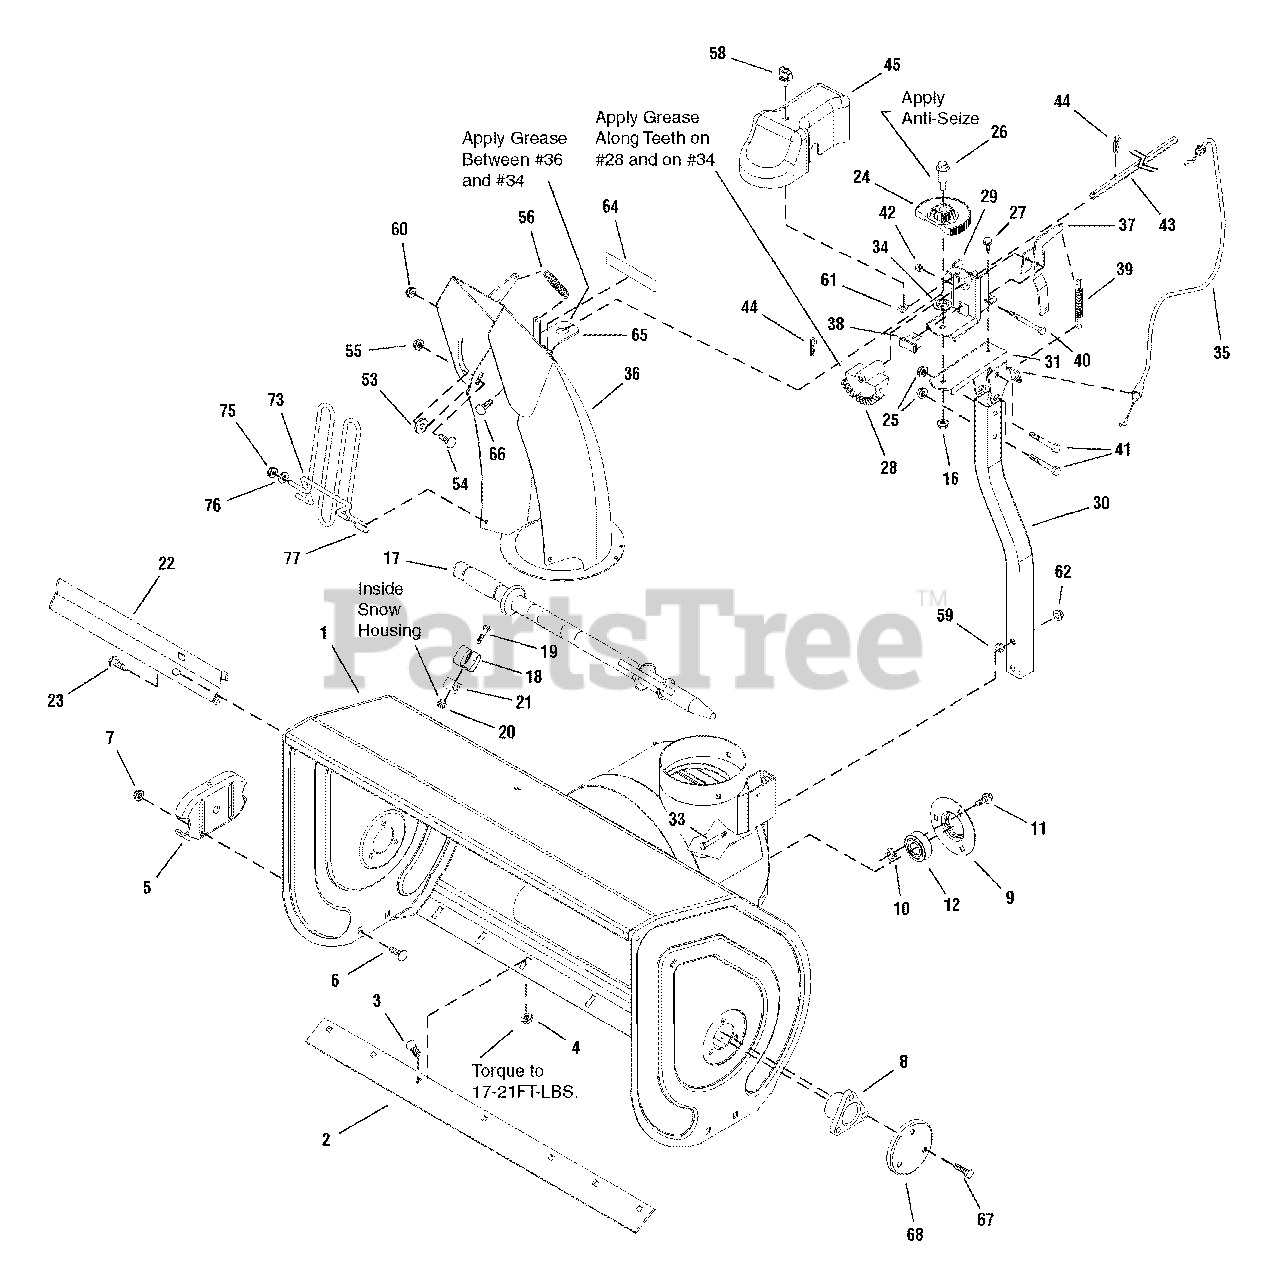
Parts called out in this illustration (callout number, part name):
1	HOUSING ASSEMBLY, 26"
1	HOUSING ASSEMBLY, 28"
1	HOUSING ASSEMBLY, 30"
1	HOUSING ASSEMBLY, 32"
2	BLADE, Scraper 26"
2	BLADE, Scraper 28"
2	BLADE, Scraper 30"
2	BLADE, Scraper 32"
3	CARRIAGE BOLT, 5/16-18 x 5/8 G5
4	NUT, Hex Flange 5/16-18 Two-Way Lock
5	SKID, Shoe Reversible
6	CARRIAGE BOLT 3/8-16 x 3/4 G5
7	NUT, Hex Flange 3/8-16 ESNA
8	BEARING, Flange
9	BEARING, Retainer
10	RETAINER, Nut, 5/16-18
11	SCREW, Hex Whiz Lock Flange 5/16-18 x 3/4
16	NUT, Hex Flange 5/16-18, Whiz Lock
17	STICK, Cleanout w/Brush
18	CLIP, Retainer
19	SCREW, Hex Washer Head Slot #10C x 1-1/4 G2
20	NUT, Hex Lock 10-24 w/Nylon Insert
21	BLOCK, Universal Pivot
22	CUTTER, Drift 12GA w/Tabs
23	SCREW, Hex Washer Head Taptite 5/16-18 x 3/4
24	GEAR, 13 Tooth
25	NUT, Hex Keps 5/16-18 Conical Washer
26	BOLT, Shoulder 5/16-18 x 3/5 G5
27	SCREW, Hex Washer Head Taptite 1/4-20 x 1/2
28	GEAR, Sector 34 Tooth Powdered Metal
29	SUPPORT, Driver Gear 12GA
30	TUBE, Square 1-1/4
31	BRACKET, Gears Support 12GA
33	CARRIAGE BOLT, 3/8-16 x 1-3/4
35	CABLE, Chute Brake 40" Long
36	CHUTE ASSEMBLY, Remote Deflector
37	BRACKET, Brake 12GA
38	ARM & PAD ASSEMBLY, Brake
39	SPRING, Extension
40	CAPSCREW, Hex Head 1/4-20 x 2-1/2 G5
41	CAPSCREW, Hex Head 5/16-18 x 2 G5
42	NUT, Hex Centerlock 1/4-20
43	ROD, Hex, Chute
44	PIN, Quick
45	COVER, Chute
53	WASHER, Nylon
54	CARRIAGE BOLT, 5/16-18 x 3/4 G5
55	NUT, Hex Flange 5/16-18 ESNA
56	SPRING, Extension
58	KNOB & SCREW ASSEMBLY, 10-24 x 3/5
59	NUT, Push Pal 3/8
60	NUT, Push
61	NUT, Retainer Speed #10-24 w/Extrusion
62	NUT, Hex Keps Conical Washer 3/8-16
64	DECAL, Orange Strip For Chute Hinge
65	BRACKET, Chute Support
66	SCREW, Pan Head Self Tap Torx 5/16 x 1/2
67	SCREW, Hex Washer Head Taptite 5j/16-18 x 1-1/4
68	COVER, Bushing
73	GUARD, Chute
75	NUT, Push Capped
76	WASHER
77	CAP
